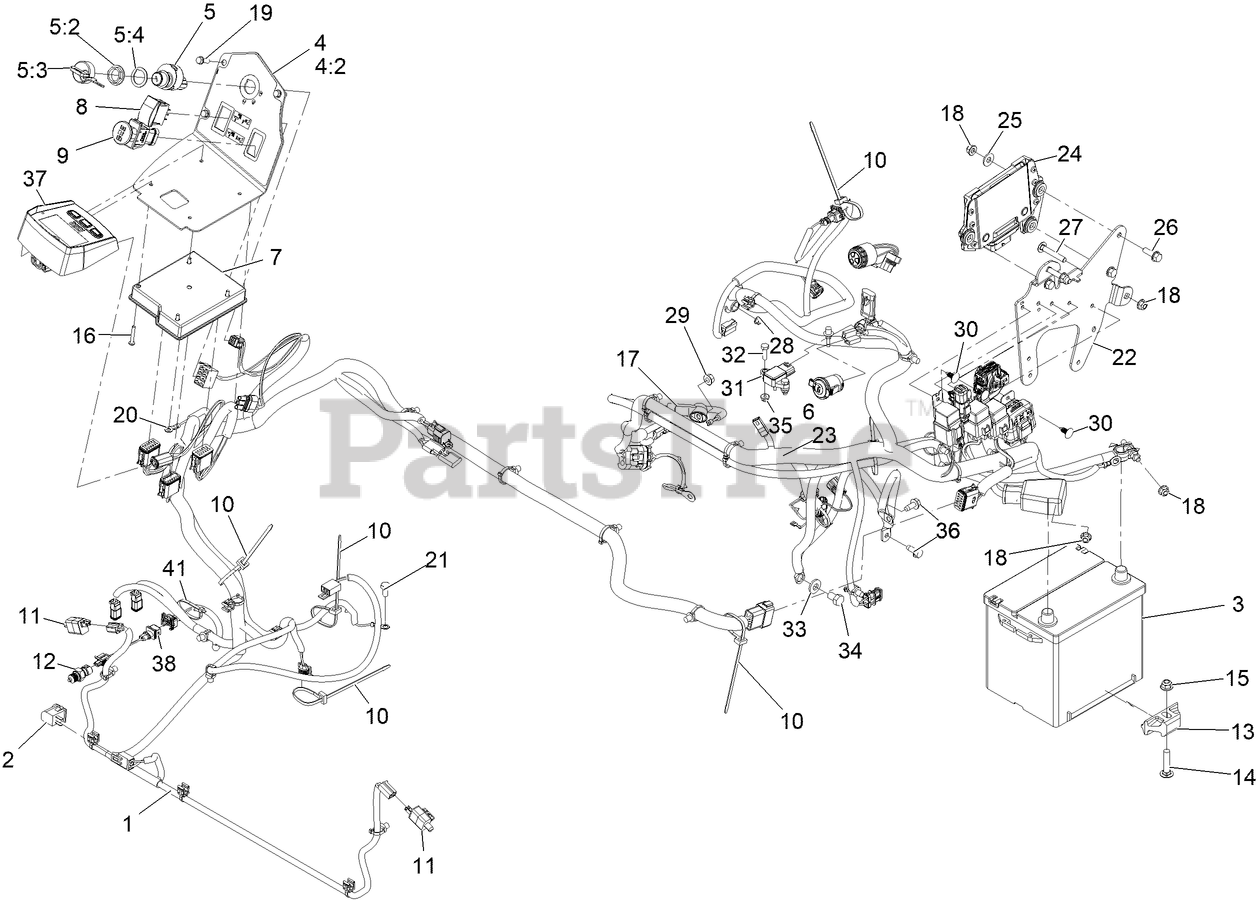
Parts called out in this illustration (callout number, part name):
1	HARNESS-WIRE
2	SWITCH-BAIL
3	Battery-Dry
4	Console ASM
4:2	DECAL-CONTROL PANEL
5	IGNITION SWITCH ASM
5:2	NUT-MOUNTING
5:3	IGNITION KEY SET
5:4	WASHER-BACKUP
6	PORT-POWER, 12V
7	Module-Mcu
9	SWITCH-PTO, SEALED
10	TIE-CABLE
12	Sensor-Temperature
13	RETAINER-BATTERY
14	SCREW-CARR
15	NUT-HF, NI
16	SCREW-PPH
17	CABLE-BATTERY
18	NUT-HF, NI
19	SCREW-HWH
20	HARNESS-WIRE, JUMPER
21	BOLT
22	BRACKET-MOUNT, ECU
23	HARNESS-WIRE, YANMAR
24	ECU ASM-SERVICE
25	WASHER-FLAT
26	SCREW-HHF
27	BOLT-CARR
30	PLUG-PLASTIC
31	SENSOR-ATM
32	SCREW-HH
33	WASHER-BELLEVILLE
34	SCREW-HH
36	Screw-HWH 5/16-18 X 3/4 Tf
37	MODULE, LDU
38	Harness-Jumper Temp Sense
41	TIE-CABLE
